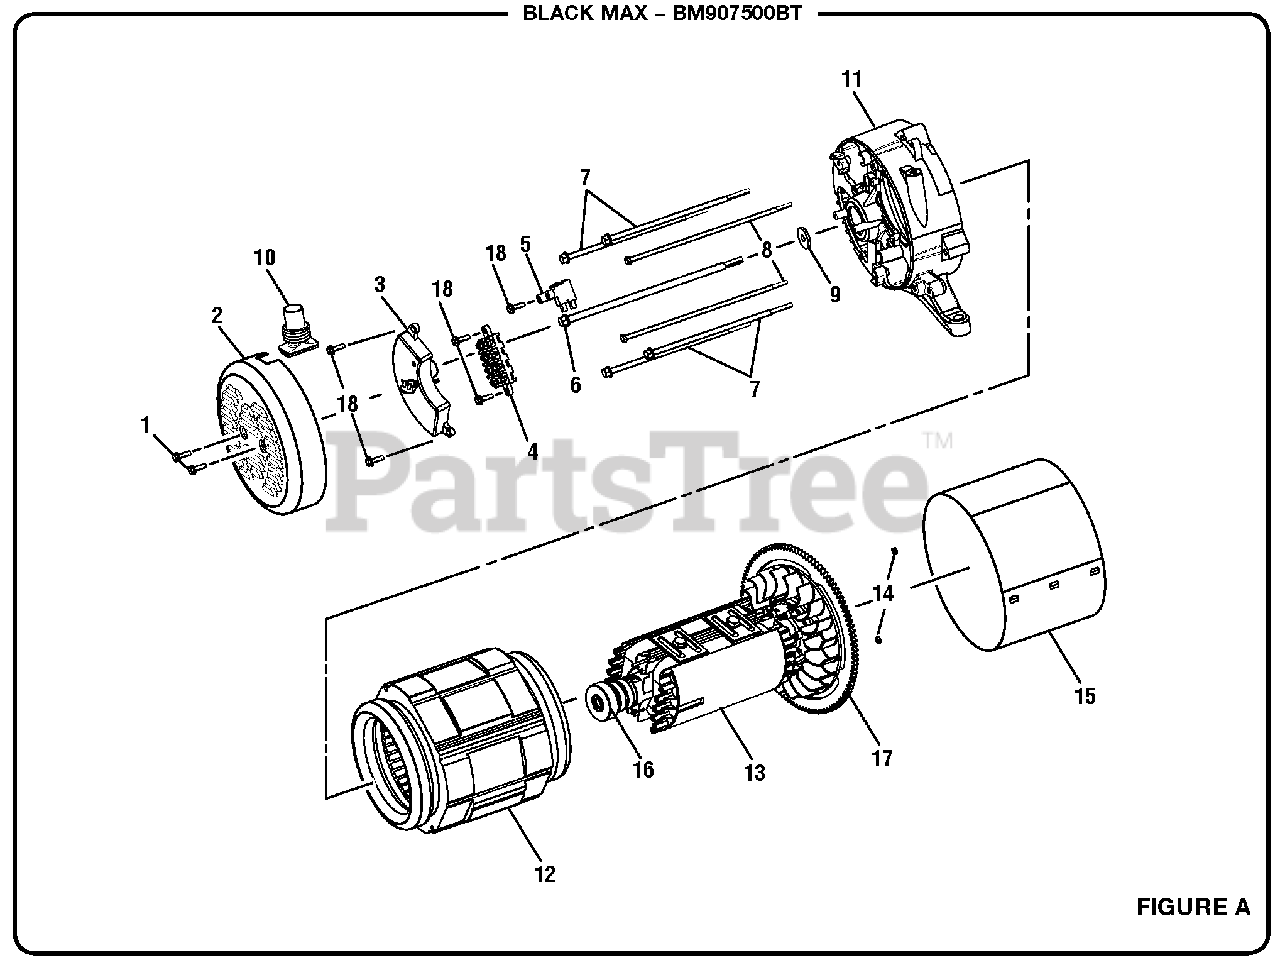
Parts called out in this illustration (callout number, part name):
1	Bolt (M5 x 16 mm, Hex Hd.)
2	Brush Cover
3	Automatic Voltage Regulator
4	Terminal Block
5	Brush Assembly
6	Bolt (5/16-24 x 260 mm, Hex Washer Hd.)
7	Bolt (M6 x 260 mm, Hex Washer Hd.)
8	Bolt (M5 x 170 mm, Hex Washer Hd.)
9	Washer (OD28 x ID10 x 3t)
10	Rubber Boot
11	Bearing Housing
12	Stator Assembly
13	Rotor Assembly
14	Hex Nut (M5)
15	Generator Head Cover
16	Ball Bearing
17	Starter Gear
18	Bolt (M5 x 12 mm, Hex Hd.)
